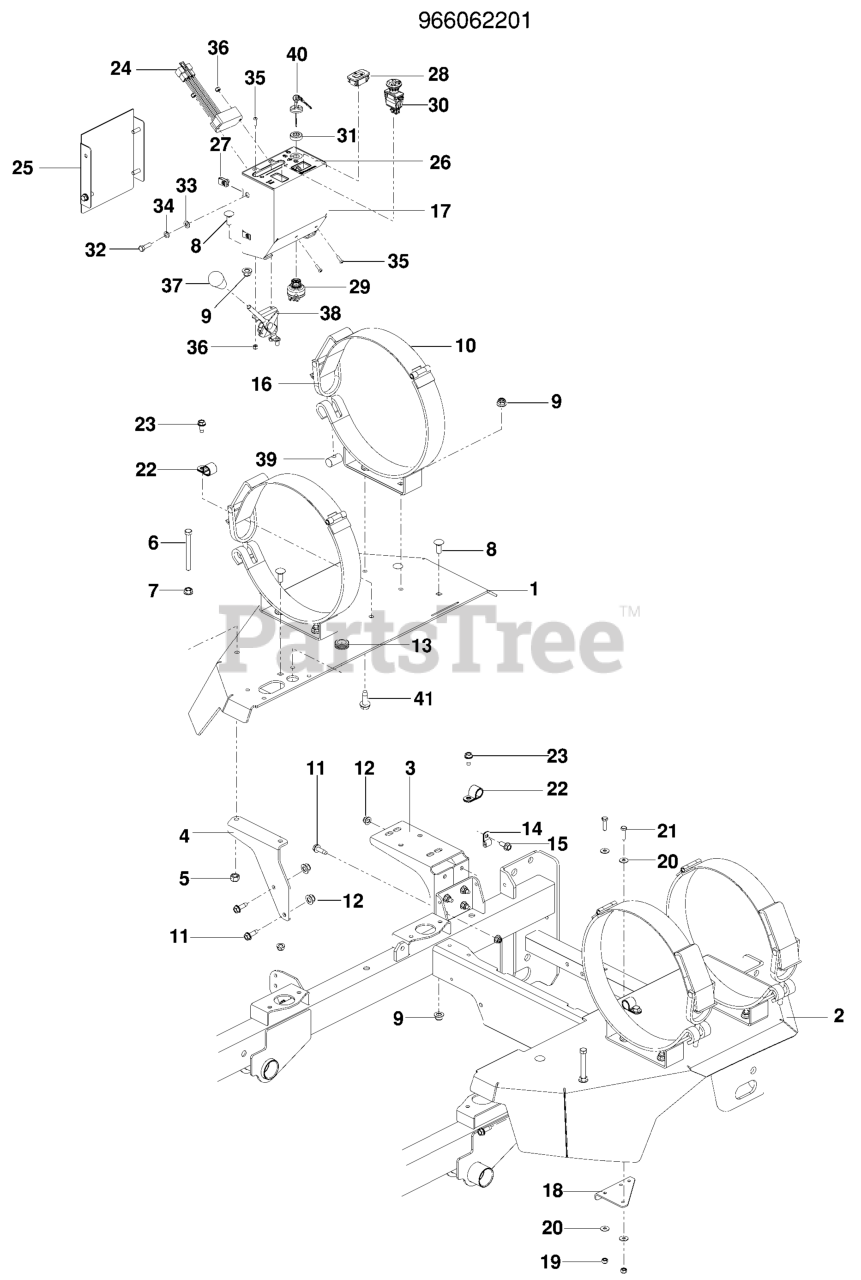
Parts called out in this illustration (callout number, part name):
1	FENDER, LP RH, ORG
2	FENDER, LP LT
3	MOUNT, TANK RR, BLK
4	SUPPORT.LP.FENDER.RH.BLACK
5	NUT 3/8C CENTERBLOCK
6	HCS 3/8-16 X 3-1/2 GR5 ZD
7	NUT 3/8C WHIZ
8	RHSNB 3/8C X 1
9	NUT 3/8-16 HEX FLG NYLOC ZD
10	LP TANK BRKT
11	RP BLT 5/16-18 X 1 THRD FORM D
12	5/16-18 NYLOC FLANGE NUT
13	GROMMET, FUEL LINE
14	DOUBLE TUBE CLAMP
15	HHFS 5/16-18 X 3/4
16	LP TOGGLE ASSY
17	DASH, LP, GRAY
18	BRACKET, REGULATOR, BLK
19	NUT.1/4-20.HEX.NYLOC.ZD
20	WASHER 1/4 FLAT
21	HCS 1/4 X 1
23	BOLT 5/16-18 X 3/4
24	TIMER, SEAT
25	COVER, LP DASH, GRAY
26	DECAL, LP CONTROL
27	U-CLIP 5/16-18 NUT RETAINER
28	HOUR METER
29	SWITCH, IGNITION, INDAK
30	SWITCH, PTO 10 AMP
31	CAP IGNITION NUT
32	HCS 5/16C X 1
33	FLAT WASHER 5/16 SAE
34	WASHER.LOCK.HVY.HLCL.SPR.5/16
35	SCR #10-24 X .75 SKT HD BLK
36	NUT 10-24 NYLOC
37	KNOB - SHIFT
38	CABLE, THROTTLE, 46"
39	NUT, TOGGLE, LP
40	KEY, IGNITION
41	HHFS 3/8-16 X 1 GRD 5 ZD
